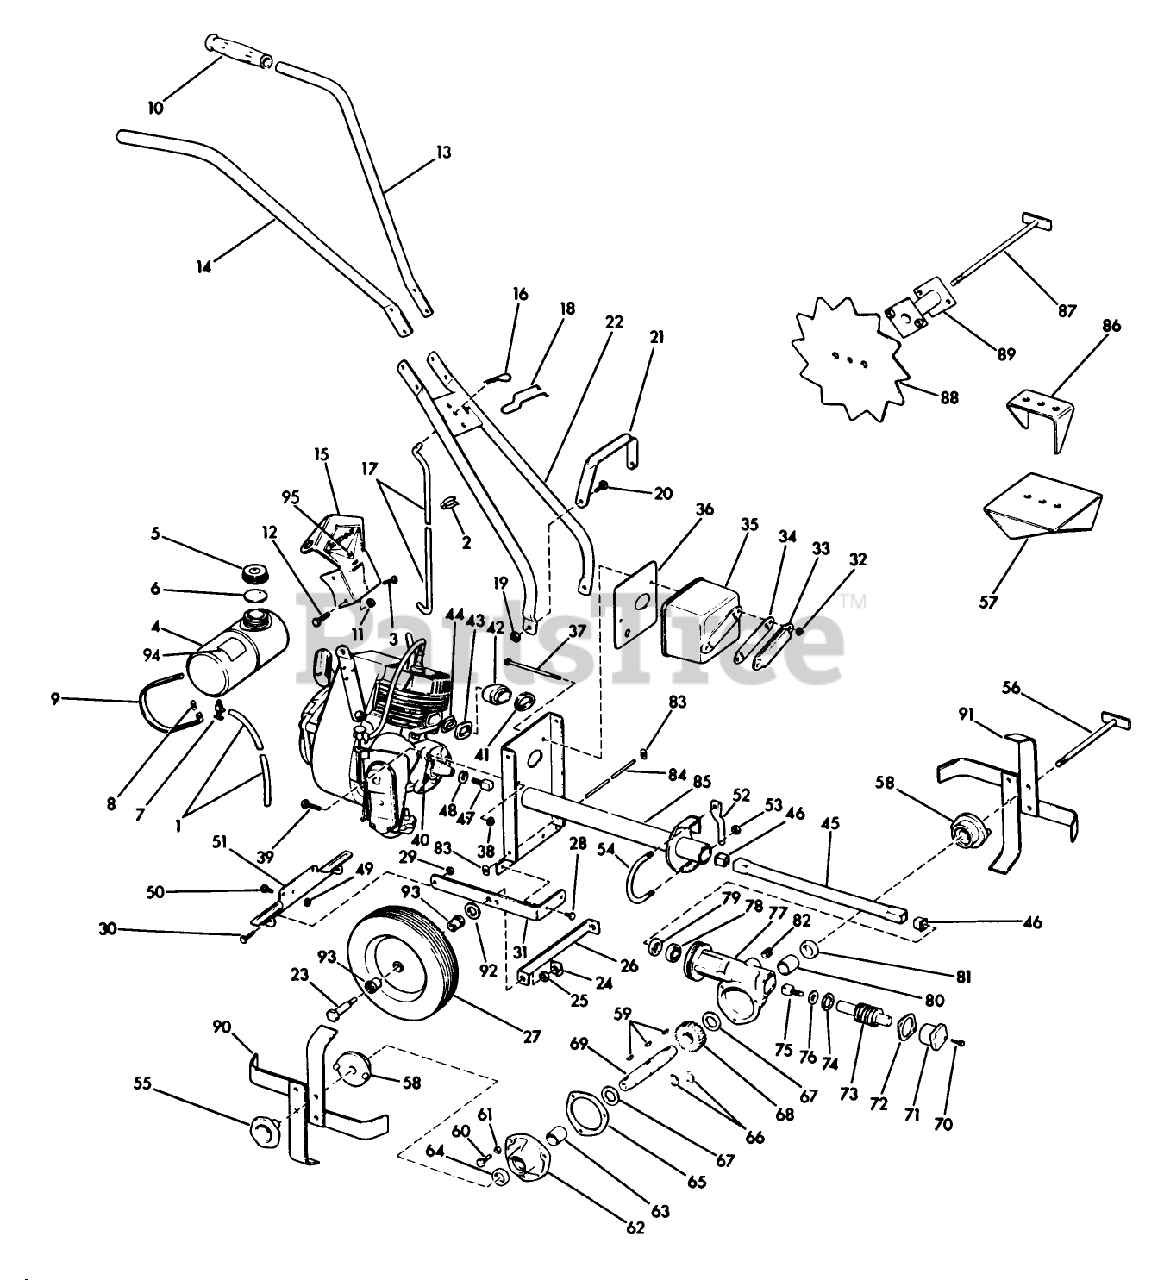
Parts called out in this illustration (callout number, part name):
1	Line-Gas
2	Clip-Gas Line
5	Gas Cap
7	VALVE&SCREEN SM
8	Nut-Speed
9	Tank Strap
12	SCREW S
14	Handle Section-Top, Right
15	Bracket-Upper Handle
17	Rod-Handle Height Adjustment
18	Guide-Starter Rope
19	Nut-Huglok
21	Bracket-Carrier Handle
25	WASHER, LOCK
26	Bracket-Center Wheel Brace
28	Screw-Thread Cutting
31	Bracket-Wheel Attachment
32	LOCKNUT E
33	Chamber-Muffler Transfer
34	Gasket-Muffler Transfer
35	Muffler
36	Gasket-Muffler
38	Nut-Huglok
41	Gasket-Exhaust
42	Sleeve-Exhaust
45	Drive Tube and Bushing Assembly
47	Screw-Square Head
48	WASHER, LOCK
50	SCREW S
51	Bracket-Wheel Scraper
52	Nut-Lever
55	Knob-Tie Rod Assembly
57	Tine-Weeder
60	SCREW S
66	Ring-Retaining
68	Worm Gear
71	Housing Cap
75	Screw-Square Head
83	Nut-Push-on
84	Rod-Wheel Scraper, Fron
86	Tine-Cultivator
88	Edging Disc
94	Decal, Instructions
